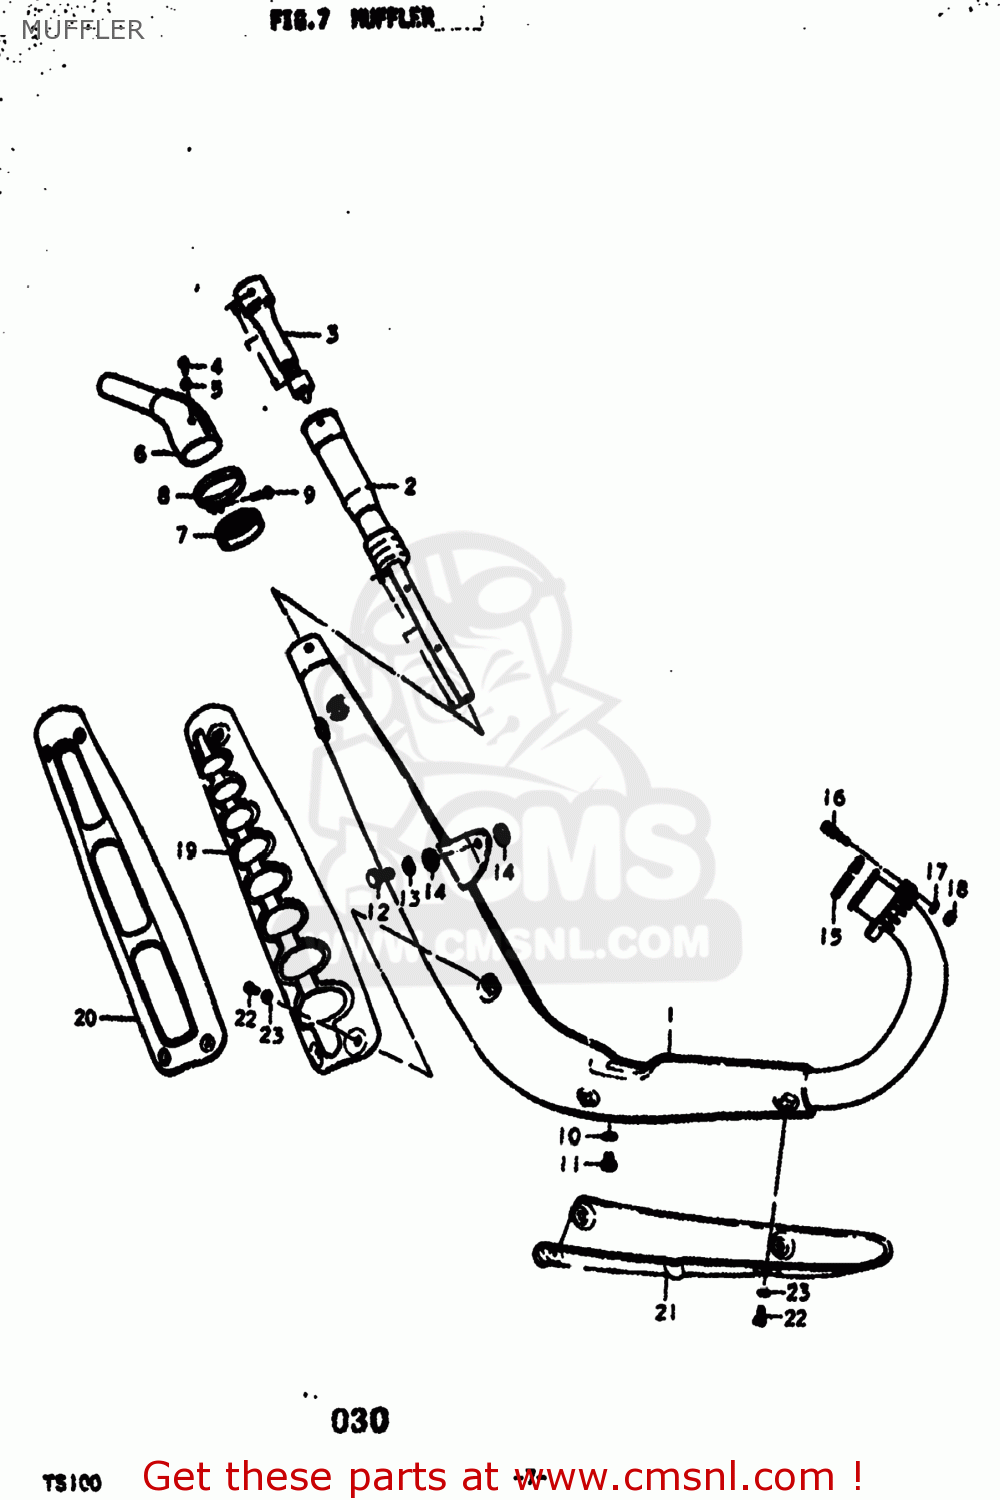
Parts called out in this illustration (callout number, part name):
1	MUFFLER ASSEMBLY
2	ARRESTER,SPARK
3	TUBE,MUFFLER CLEAN OUT
4	SCREW 6X12
5	GASKET
6	EXHAUST EXTENSION
7	GASKET,MUFFLER TAIL PIPE (NAS)
8	CLAMP
9	SCREW
10	GASKET(10X14X3.6) (NAS)
11	BOLT 10X9
12	BOLT
13	LOCK WASHER
14	WASHER
15	GASKET,EXHAUST PIPE (NAS)
16	STUD
17	LOCK WASHER
18	NUT
19	COVER,MUFFLER
20	COVER,MUFFLER
21	COVER,MUFFLER
22	SCREW
23	LOCK WASHER
